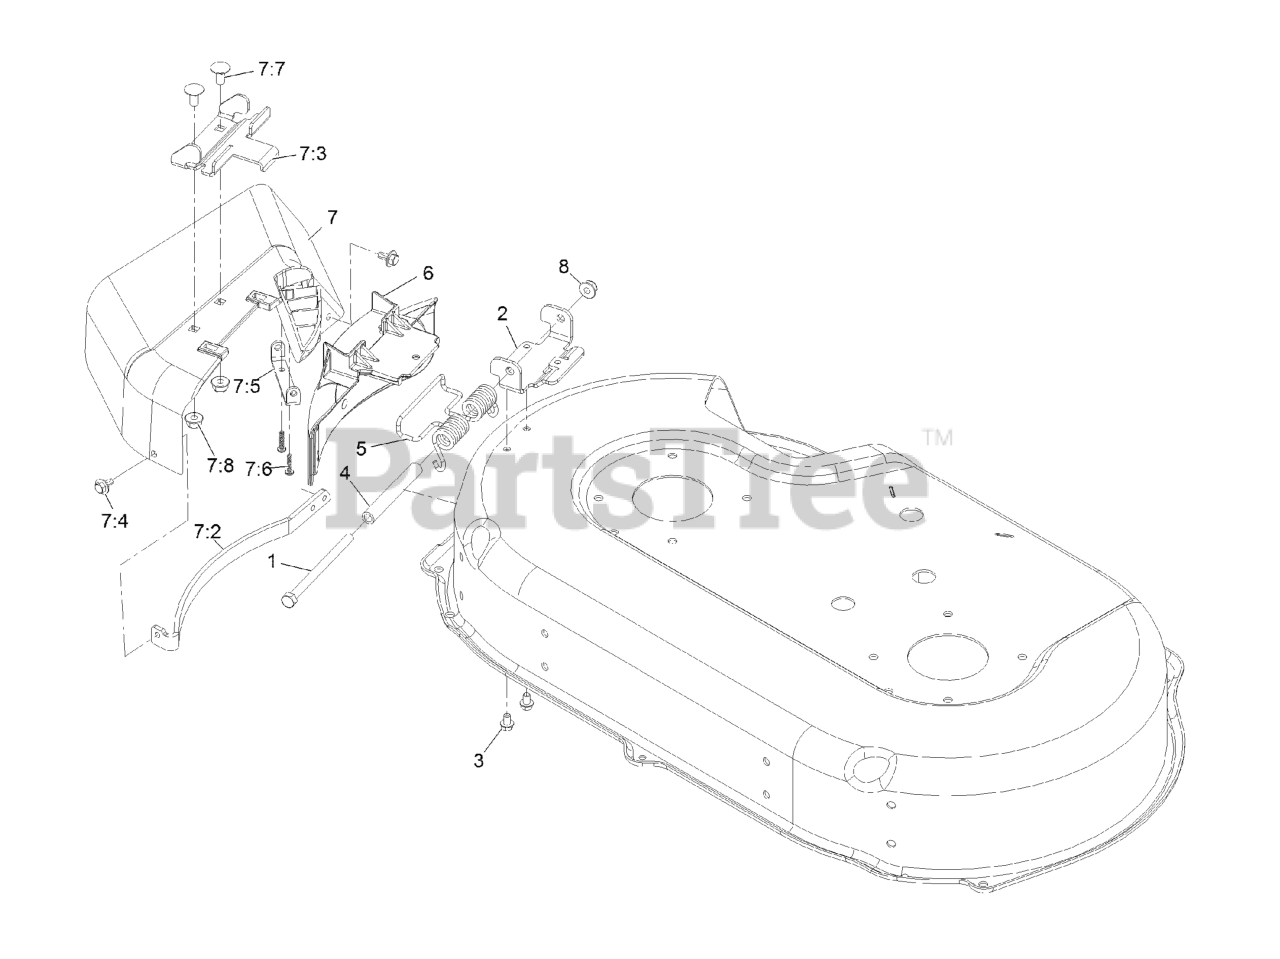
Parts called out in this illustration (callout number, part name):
1	SCREW-HH
3	SCREW-HWH
5	SPRING-TORSION
6	COVER-DISCHARGE
7	SIDE DISCHARGE CHUTE ASM
7:2	GUARD-CHUTE
7:3	BRACKET-CHUTE
7:4	SCREW-HHFTF
7:5	BRACKET-COVER
7:6	SCREW-PPH
7:7	SCREW-CARR
7:8	NUT-HF, NI
8	NUT-HF, NI
